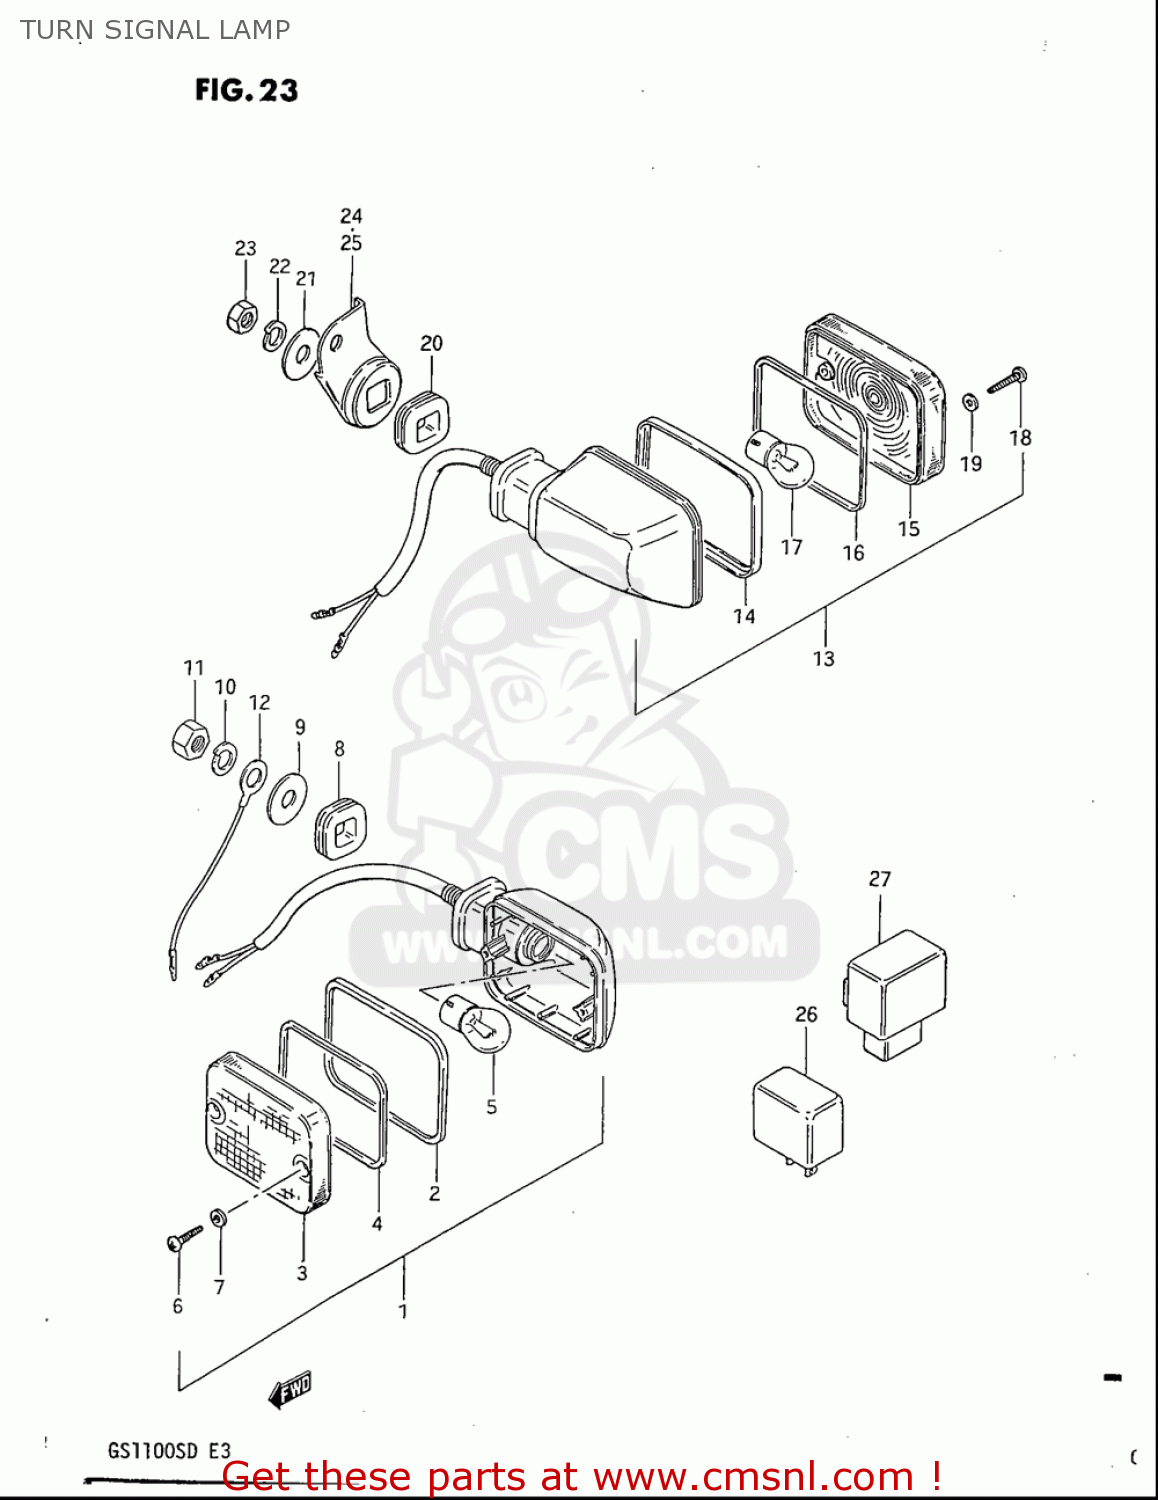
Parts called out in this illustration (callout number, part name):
1	LAMP ASSY,FR TURN SIGNAL
2	RIM
3	LENS
4	GASKET (NAS)
5	BULB(12V23W)
6	SCREW
7	GASKET (NAS)
8	CUSHION
9	WASHER(10.5X30X2.3)
10	WASHER,LOCK
11	NUT
12	WIRE,TURN SIGNAL LEAD
13	LAMP ASSEMBLY,FRONT TURN SIGNAL
14	RIM
15	LENS
16	GASKET (NAS)
17	BULB(12V23W,STANLEY,A4577A)
18	SCREW
19	GASKET (NAS)
20	CUSHION
21	WASHER(10.5X30X2.3)
22	WASHER,LOCK
23	NUT
24	BRACKET,RR TURNSIGNAL LAMP,R
25	BRACKET,RR TURNSIGNAL LAMP,L
26	RELAY ASSY,TURNSIGNAL
27	UNIT,TURN SIGNAL CONTROL
